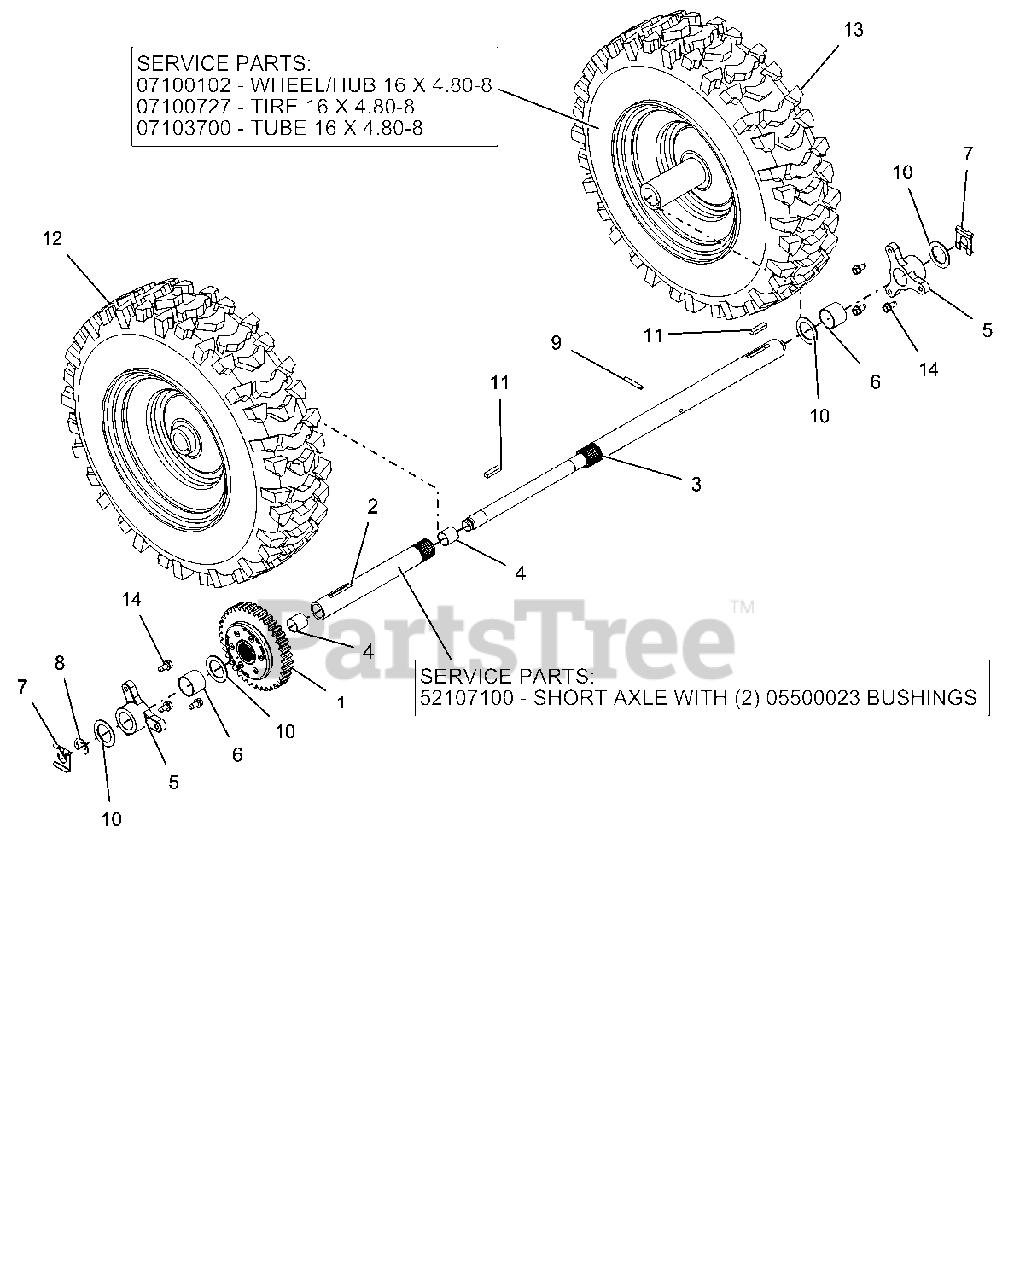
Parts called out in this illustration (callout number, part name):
1	DIFFERENTIAL, AUTOMATIC
2	SHORT AXLE
2	BUSHING
2	AXLE, SHORT - DIFFERENTIAL
3	AXLE, LONG - DIFFERENTIAL
4	BSHG, SLV .706 X .764 X .75 BRZ
5	BSHG, AXLE
6	BSHG, SLV 1.012 X 1.125 X .875
7	CLIP, SNAP - .625
8	RING, RETAINING-E .625X.042
9	PIN-ROLL .188X1.25
10	WSHR-FL-STL 1.010X1.505X.062 YWZC
11	KEY, RECT .25X.188X1.00
12	TIRE/WHEEL, RH 16X4.80-8 KEY
13	WHEEL/HUB 16 X 4.80-8
13	TIRE 16 X 4.80-8
13	TUBE 16 X 4.80-8
13	TIRE/WHEEL, LH 16X4.80-8 KEY
14	SCR-TAP .25-20X.50 HWH TR YWZ
